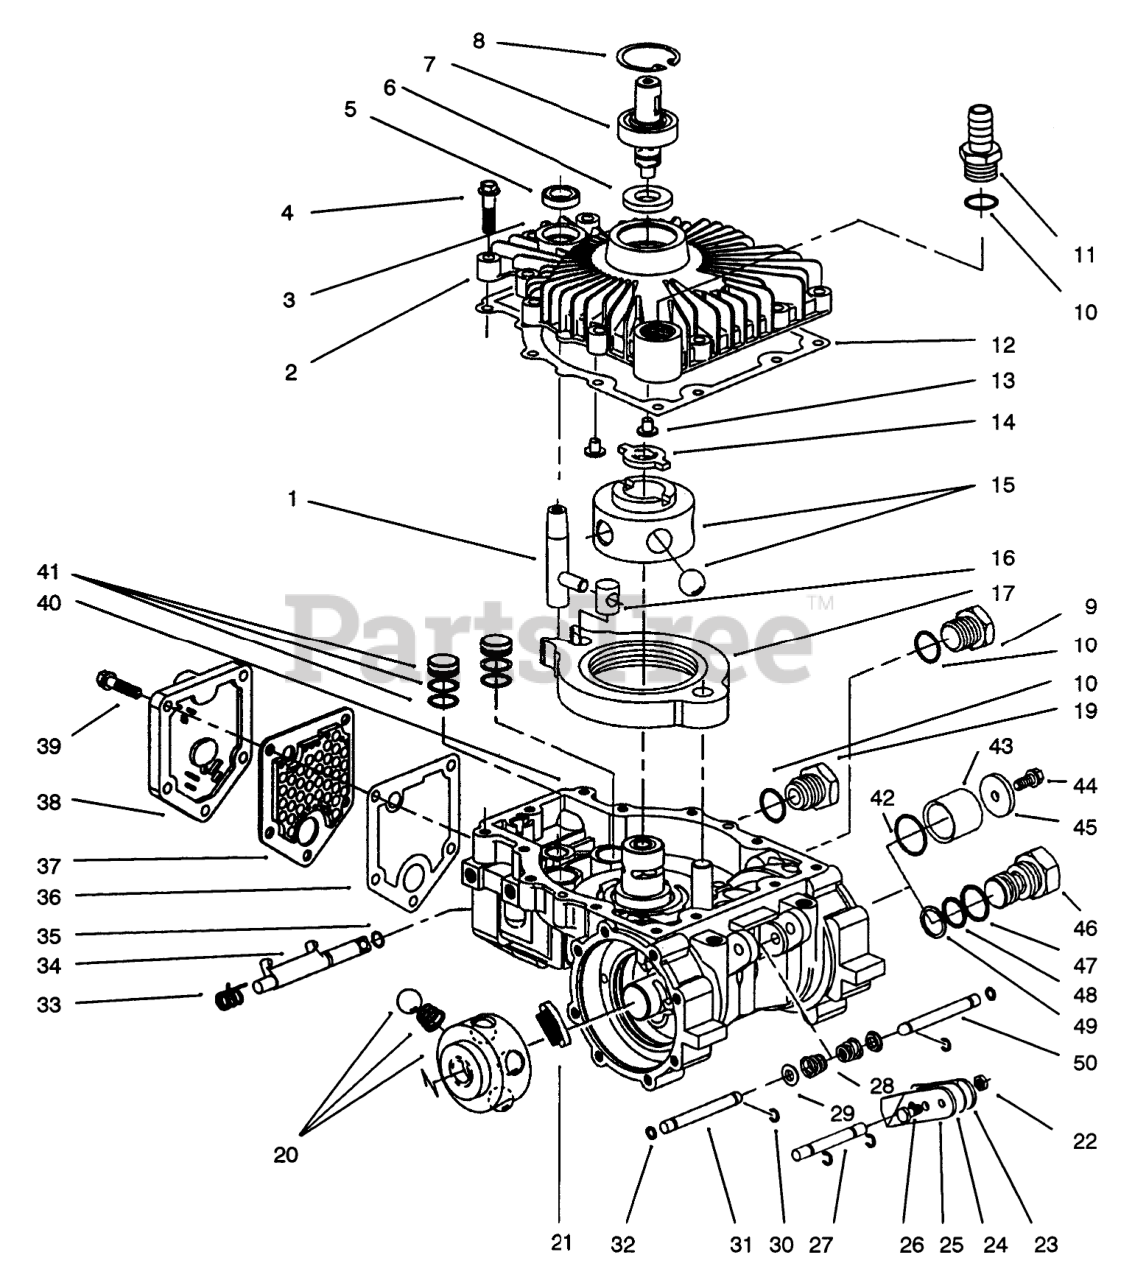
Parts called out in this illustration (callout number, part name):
1	CONTROL SHAFT
2	Cover Assembly (Incl. Ref. #3, 5-8)
3	COVER
4	1/4-20 SCREW
5	SEAL-OIL
6	Seal
7	INPUT SHAFT
8	Retaining Ring
9	Plug Assembly (Incl. Ref. #10)
10	"O" RING SEAL
11	Fitting 90deg.
12	COVER GASKET
13	Button
14	DRIVE
15	PUMP ASM
16	INSERT
17	CAM RING ASM
19	ROTOR BALL ASM
20	ROTOR BALL ASM
21	FRICTION PAD
22	LOCKNUT
23	RH BRAKE LEVER
25	LH BRAKE LEVER
26	HEX HEAD SCREW
27	BRAKE SHAFT
28	CONICAL SPRING
29	SPRING BASE
30	RETAINING RING
31	PUSH ROD
32	QUAD SEAL
33	DUMP VALVE SPRING
34	DUMP VALVE BRACKET
35	SEAL "O" RING
36	FILTER GASKET
37	FILTER
38	VALVE COVER
39	1/4-20 HEX HEAD SCREW
40	HOUSING ASM
41	PISTON ASM
42	"O" RING SEAL
43	CUP SEAL
45	WASHER
47	"O" RING SEAL
48	"O" RING SEAL
49	BACKUP RING
50	PUSH ROD
